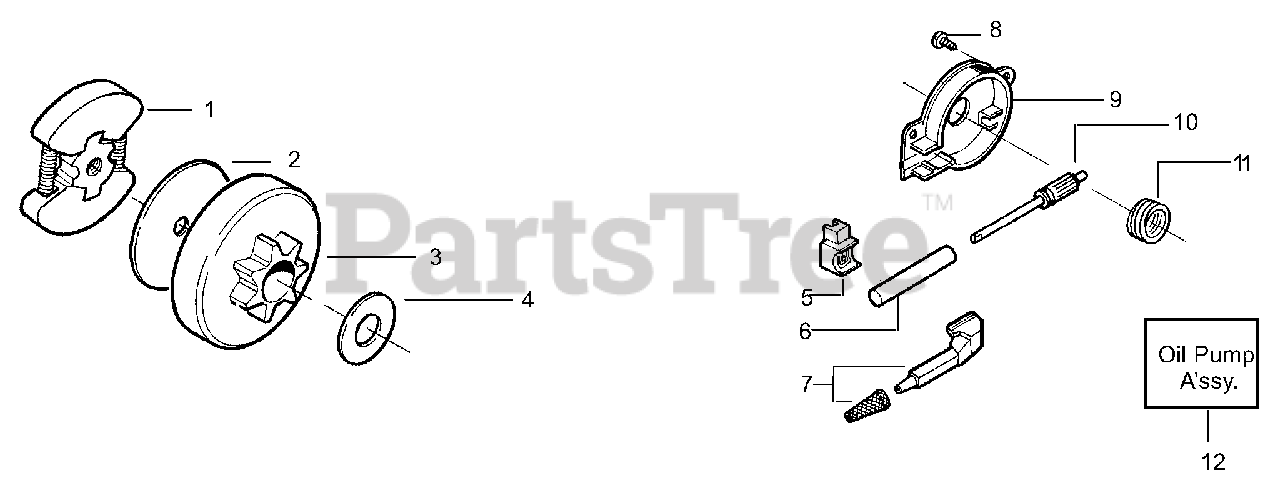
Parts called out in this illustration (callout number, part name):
1	Assy-Clutch
2	Washer-Clutch
3	Assy-Clutch Drum w/Bearing
4	Washer-Thrust
5	Seal-Oil
6	Barrel-Oil Pump
7	Assy-Oil Pick-Up and Screen
9	Housing-Oil Pump
10	Assy-Plunger & Gear
11	Worm-Oil Pump
12	Assy-Oil Pump
